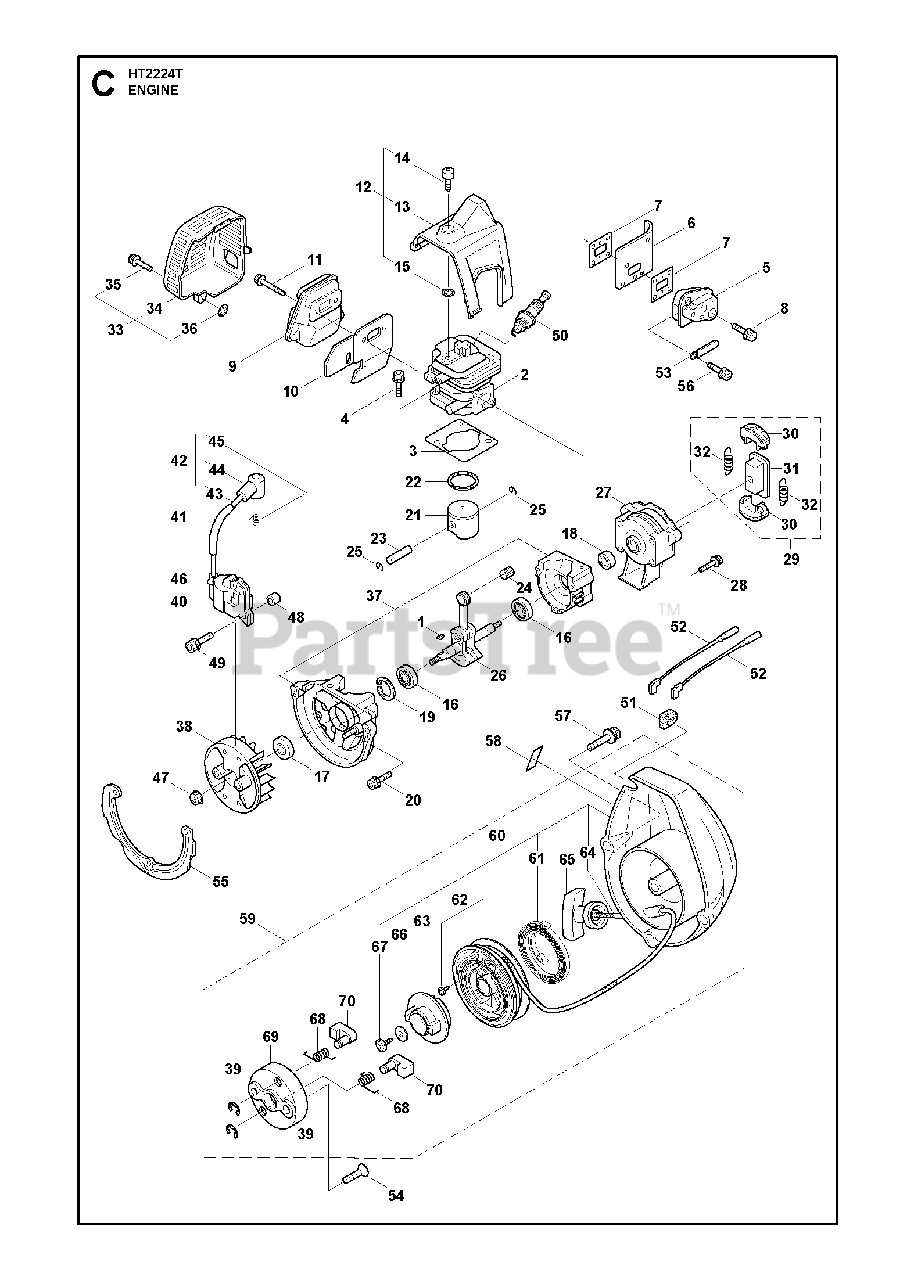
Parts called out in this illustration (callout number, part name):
2	CYLINDER/CARB
3	BASE GASKET
5	INSULATOR
10	HEAT SHIELD/GASKET
14	KNOB
16	BALL BEARING
17	SEALING RING
18	SEALING RING
23	PISTON PIN
26	CRANKSHAFT
27	CLUTCH COVER
30	CLUTCH
32	SPRING
37	CRANKCASE COMPLETE
39	RETAINING RING
40	IGNITION MODULE
41	INSULATOR
43	CABLE
44	SPARK PLUG CONNECTION
45	SPRING
61	RETURN SPRING
62	STARTER PULLEY/SPRING ASSY
63	STARTER PULLY
64	STARTER ROPE
66	WASHER
67	SCREW
68	RETURN SPRING
69	HOUSING
70	PAWL
